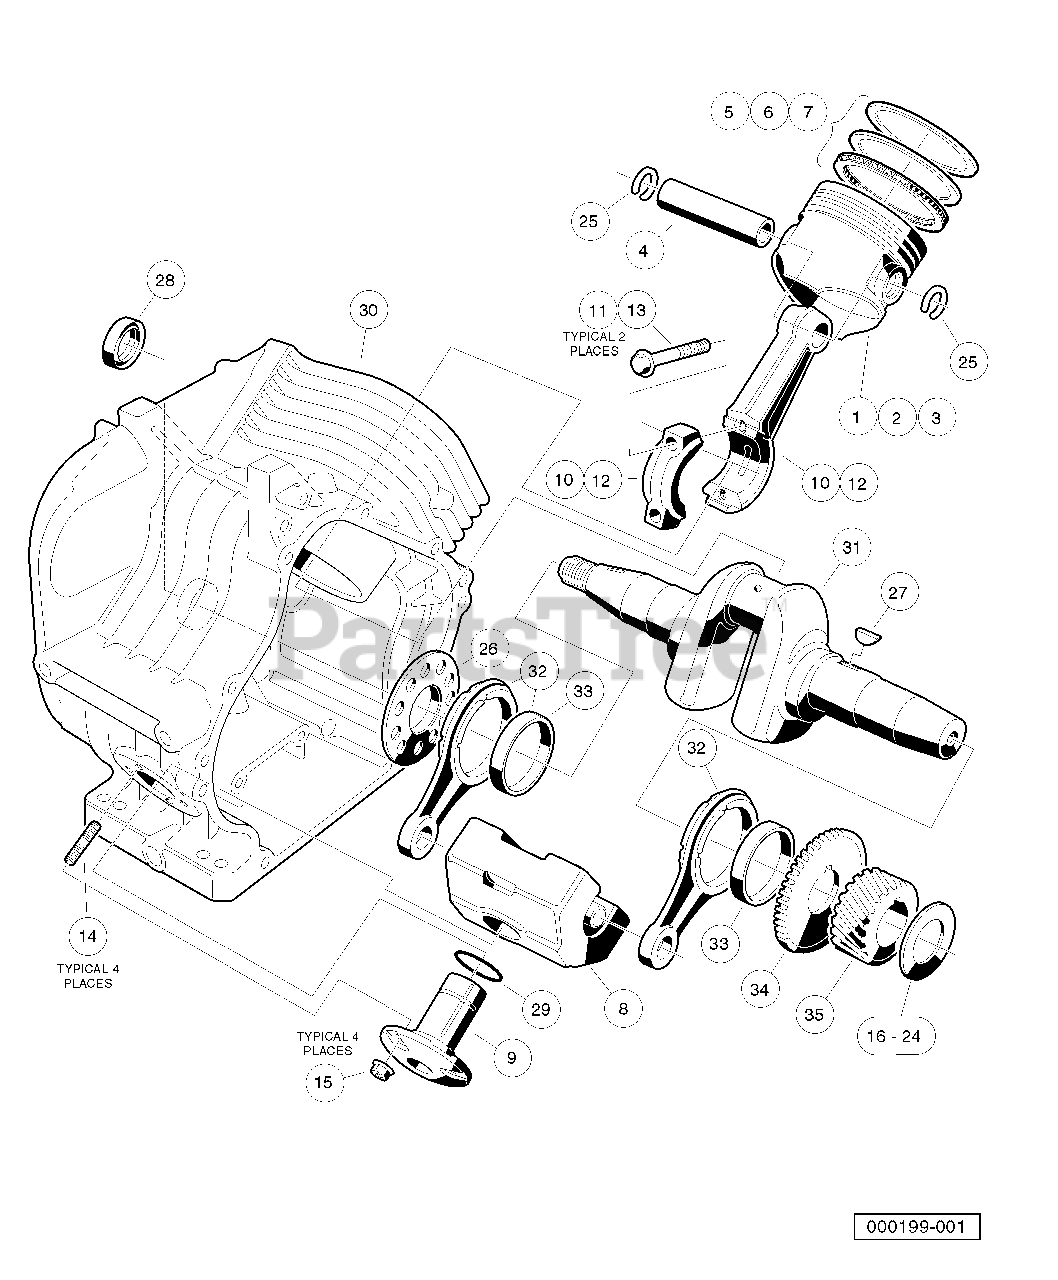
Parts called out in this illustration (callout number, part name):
2	Piston, Engine 0.25 mm Over
3	Piston, Engine 0.50 mm Over
4	Pin, Piston
5	Ring Set, Piston
6	Ring Set, Piston 0.25 mm Over
7	Ring Set, Piston 0.50 mm Over
8	Weight, Counterbalance
9	Shaft, Guide, Counterbalance
10	Rod Assembly
12	Rod Assembly, Connecting 0.50 mm Under
14	Stud, 6x14
16	Shim, Crankshaft T=1.13
17	Shim, Crankshaft T=1.18
18	Shim, Crankshaft T=1.23
19	Shim, Crankshaft T=1.28
20	Shim, Crankshaft T=1.33
21	Shim, Crankshaft T=1.38
22	Shim, Crankshaft T=1.43
23	Shim, Crankshaft T=1.48
24	Shim, Crankshaft T=1.53
25	Ring, Snap
30	Crankcase Complete, FE290
31	Crankshaft, FE290 Left-Hand Thread
32	Rod
33	Bearing, Plane
34	Gear, Spur
35	Gear, Helical
